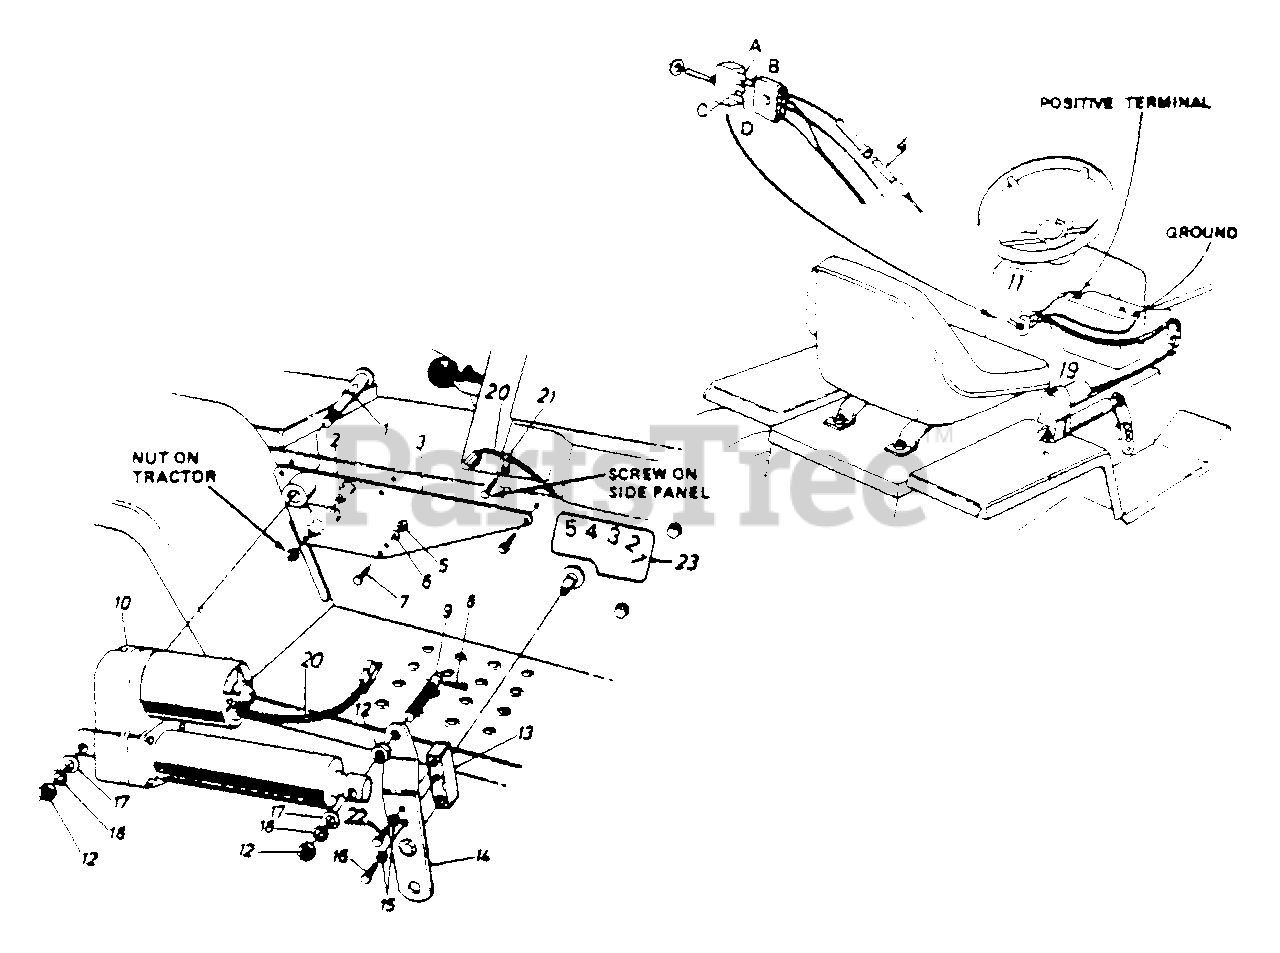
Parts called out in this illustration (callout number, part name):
1	Pivot Pin
2	Shld. Bolt .626 Dia x .96"
5	Hex Nut 1/4-28 Thd.
6	L-Wash. 1/4" I.D.
7	Hex Bolt 1/4-28 x .75" Lg. (Grade 5)
8	Cotter Pin
9	Indicator & Mtg. Pin
10	Electric Actuator
12	Hex Jam Nut 1/2-13 Thd.
13	Lift Shaft Drive
16	Hex Bolt 5/16-24 x 1.0" Lg. (Grade 5)
17	Fl-Wash..53" I.D x 93" O.D.
18	L-Wash. 1/2" I.D.
19	Wire Harness
20	Plastic Tubing-7"
21	Clamp
22	Hex Bolt 5/16-18 x 1" Lg (Grade 5)
23	Label WIRING
